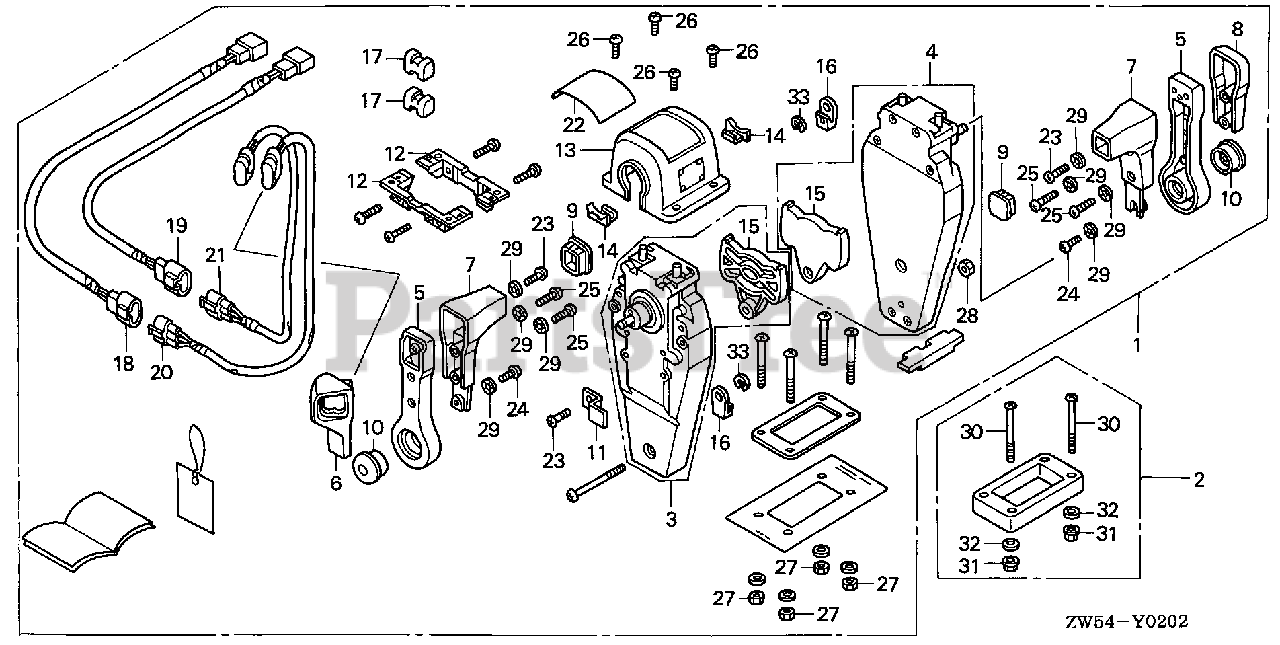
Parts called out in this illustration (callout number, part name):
1	BOX KIT, REMOTE CONTROL
2	SPACER KIT, REMOTE CONTROL BOX
3	HOUSING ASSY., L. (INNER)
4	HOUSING ASSY., R. (INNER)
5	HANDLE, REMOTE CONTROL
6	COVER, L. GRIP
7	GRIP, REMOTE CONTROL HANDLE
8	COVER, DUAL GRIP
9	CAP, GRIP
10	BUTTON, THROTTLE
11	PLATE, CABLE CLAMP
12	BRACKET, REMOTE CONTROL
13	HOUSING, DUAL REMOTE CONTROL
14	HOUSING, LEAD
15	PLATE, DWELL
16	TERMINAL, CABLE
17	SPACER, CABLE CLAMP
18	SUB-HARNESS ASSY., POWER
19	SUB-HARNESS ASSY., POWER
20	SWITCH ASSY., POWER TRIM-TILT
21	SWITCH ASSY., POWER TRIM-TILT
22	MARK, REMOTE CONTROL (DUAL)
23	SCREW, PAN (5X16)
24	SCREW, PAN (5X10)
25	SCREW, PAN (5X20)
26	SCREW, PAN (4X10)
27	NUT, HEX. (5MM)
28	NUT, HEX. (5MM)
29	WASHER, LOCK (5MM)
30	SCREW, PAN (5X65)
31	NUT, FLANGE (5MM)
32	WASHER, PLAIN (5MM)
33	E-RING (6MM)
